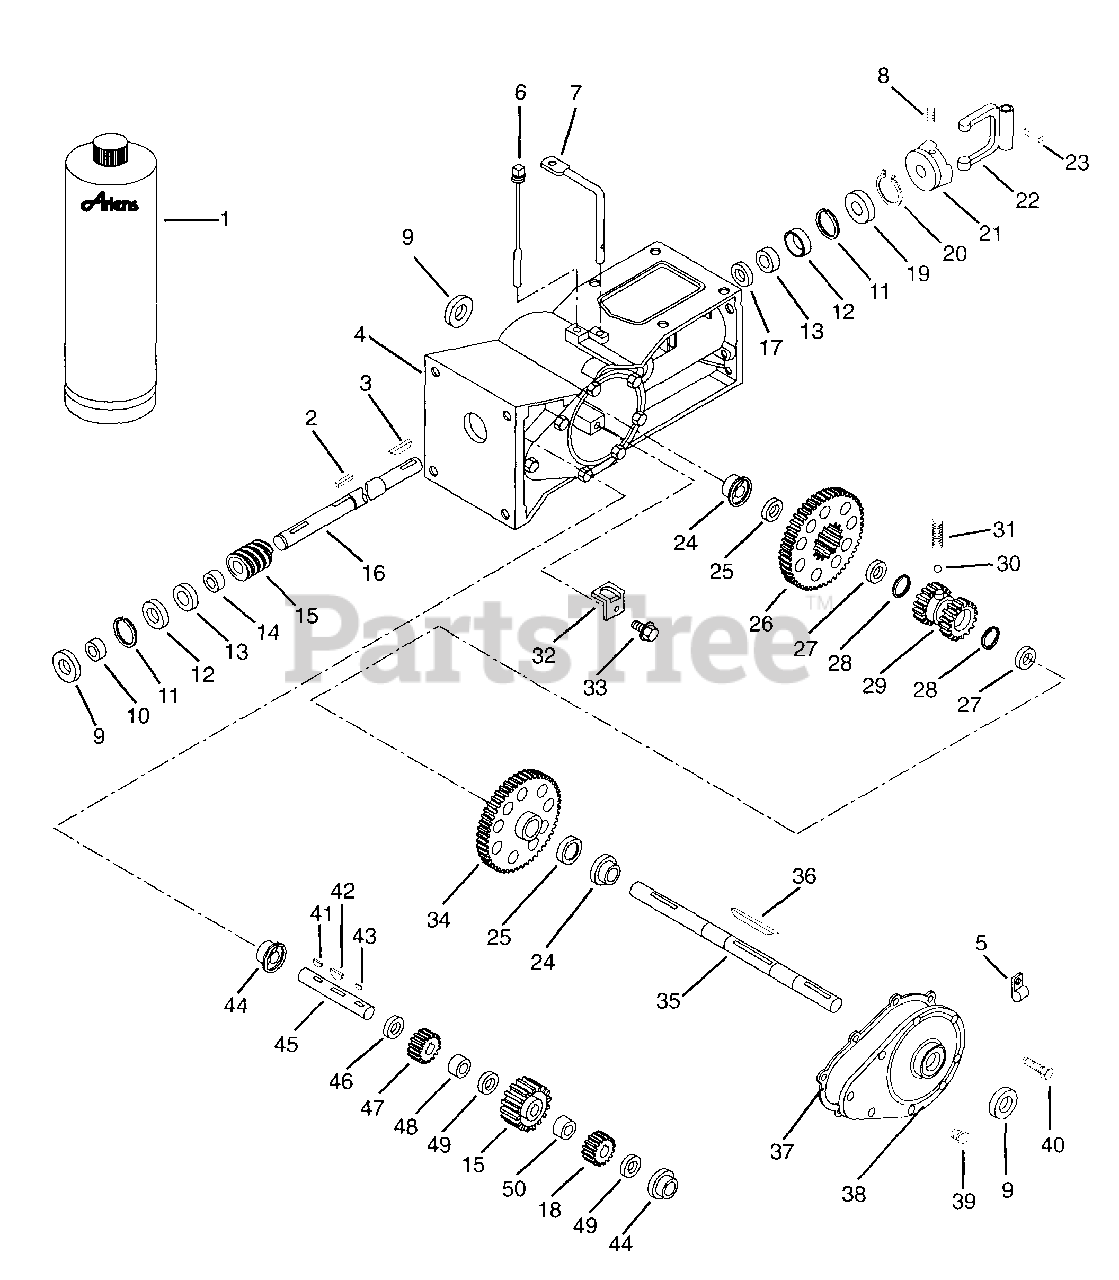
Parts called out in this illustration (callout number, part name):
1	ARIENS 16 OZ.BOTTLE OF L2 LUBE
2	KEY-SQ .188X1.0X.188 SAE 8630
3	KEY-FTHR .188X1.25X.187 SAE
4	TRANSMISSION HOUSING
5	CLAMP, CUSHIONED STEEL
6	DIP STICK
7	HIGH-LOW SHIFT LEVER
8	SCR-SET .32-18X.38 SKHCUPNL OH
9	SEAL 1.000X1.785X.250
10	SPACER BUSHING .99 X .75 X .50
11	RG-RTNG-INT 1.781X.052
12	BRG-CUP 1.781X.475
13	BRG-CONE .750X.61
14	BSHG, SPCR .755X1.12X.50 PM
15	WORM AND WORM GEAR
16	WORM SHAFT
17	WSHR-FL-STL .755X1.375X.125
18	LOW PINION
19	SEAL .750X1.781X.250
20	RG-RTNG-EXT .750X.078
21	TILLER DRIVING JAW
22	SHIFT YOKE
23	PIN-ROLL .250X1.00
24	BSHG-FLG 1.000X1.25X1.000X1.50
25	WSHR-HRD-THRS 1.007X1.542X.062
26	HIGH GEAR ASSY
28	RG-RTNG-EXT 1.00X.078
29	CLUTCH HUB
30	STEEL BALL
31	SG-COMP .047X.31X.593 WLD11
32	RETAINER CLIP
33	SCR-TAP 10-24X.75 HWH TR YWZC
34	LOW GEAR
35	AXLE SHAFT
36	KEY-FTHR .25X2.75X.25 SAE1035
38	TRANSMISSION COVER
39	PIPE PLUG
40	SCR-TAP .312-18X1.00 HWH YWZC
41	KEY-WDRF .188X.625X.31 SAE9MOD
42	KEY-WDRF .25X.687X.375
43	KEY-WDRF .188X.75X.313 SAE 9
44	BSHG-FLG .750X1.000X.750X1.250
45	SHAFT, PINION
46	WSHR-HDND-THRST .760X1.25X.094
47	HIGH PINION
48	SPACER 1.25 X .75 X .75
49	WSHR-HDND-THRST .758X1.23X.031
50	SPACER 1.25 X .75 X .75
